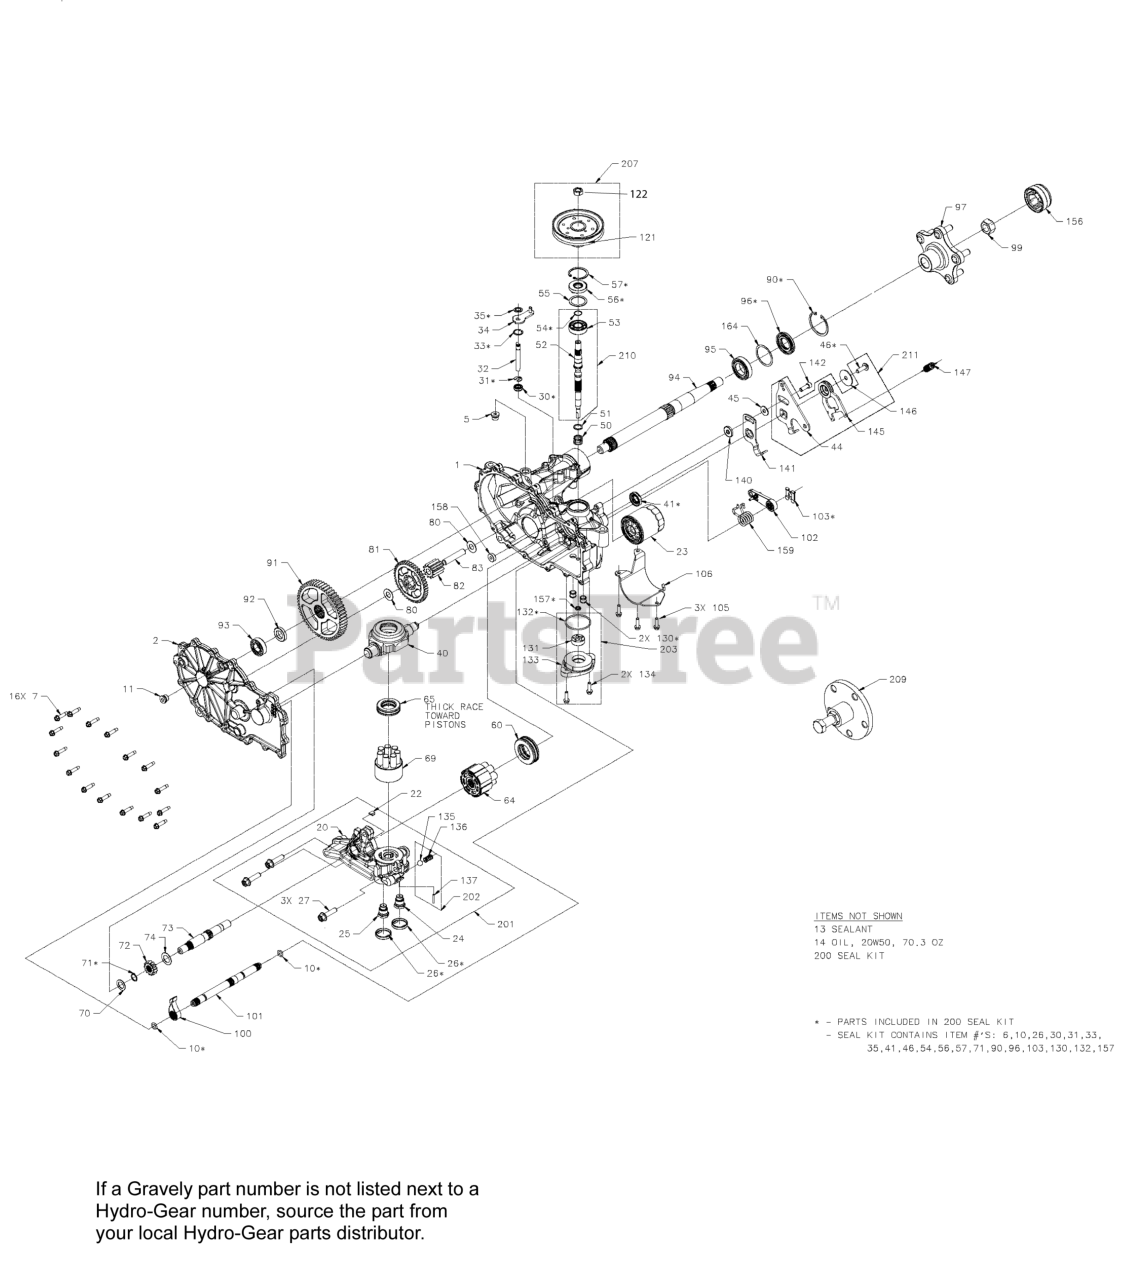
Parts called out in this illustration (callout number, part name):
1	KIT, HOUSING,MAIN,LH,CHRG,CNTL
2	KIT, COVER, SIDE, LH
5	PLUG, 9/16 18 METAL
7	SCREW,HEX WASHER 1/4-20X1.125
11	PLUG, 9/16 18 METAL
13	SEALANT TUBE 10.1OZ.
14	FLUID, HYDRO 15W50 QT
14	FLUID, HYDRO 20W50 QT
22	PLATE, BYPASS
23	FILTER, HYDRO-GEAR 2800 TRANS
26	SEAL, PLUG 1.375 X .250
27	HFHCS 3/8-16X1.5 (PATCH)
30	SEAL, LIP .375X.75X.25
31	RING. RETAINING
32	ROD, BYPASS
33	RING, RET .750
34	HG BYPASS ARM (52370)
35	RING, RTNG .
40	TRUNNION, SWASHPLATE
41	SEAL, LIP 18X32X7
46	TWHCS 5/16-24 X 1.00
50	SPRING. BLOCK
51	WASHER. THRUST .59 X .79 X .04
55	WASHER 1.23X1.56X.04
56	SEAL, LIP 17X40X7
57	RING, RET 1.56 INT
60	HG THRUST BEARING (51462)
64	HG 16CC CYLINDER BLOCK (71579)
65	HG THRUST BLOCK (53502)
69	ASSY, BLOCK 7 PISTON
70	WASHER .63X1.0X.05
71	RING, RET 62 EXT
72	GEAR, 13T, STEEL
73	SHAFT, MOTOR
74	WASHER .71 X 1.16 X .04
80	WASHER .5X1.0X.032
82	GEAR 11 TOOTH STEEL
83	JACK SHAFT (PIN)
90	RING, RETAINING
91	GEAR, 54T
94	SHAFT, AXLE
96	SEAL, LIP 28 X 52 X 7 TC
97	HUB, HYDROGEAR P/N 71691
100	PAWL, BRAKE
101	SHAFT, BRAKE
102	KIT, BRAKE ARM
103	CLIP, RETAINING
106	GUARD, FILTER, LH
121	PULLEY, 4.5 INCH
122	NUT, HEX 1/2-20 PATCH
130	TUBE, CONNECTING
132	O-RING HYDROGEAR 52250
133	COVER, CHARGE PUMP
141	ARM, NEUTRAL LEFT
142	SHCS 5/16-24X1 PATCH
147	SPRING, HYDROGEAR P/N 51833
157	SEAL, LIP 8 X 12 X 3 VC
158	MAGNET, RING
159	SPRING, TORSION, CW
164	WASHER, 1.355 x 2.035 x .021 FLAT
200	KIT, SEAL
201	KIT, CENTER SECTION, LH, CHRG
202	KIT CHARGE RELIEF
203	KIT, CHARGE PUMP
209	HUB PULLER 5 BLT
210	INPUT SHAFT HG 71978
211	TRN KIT HRDROGEAR P/N 71599
